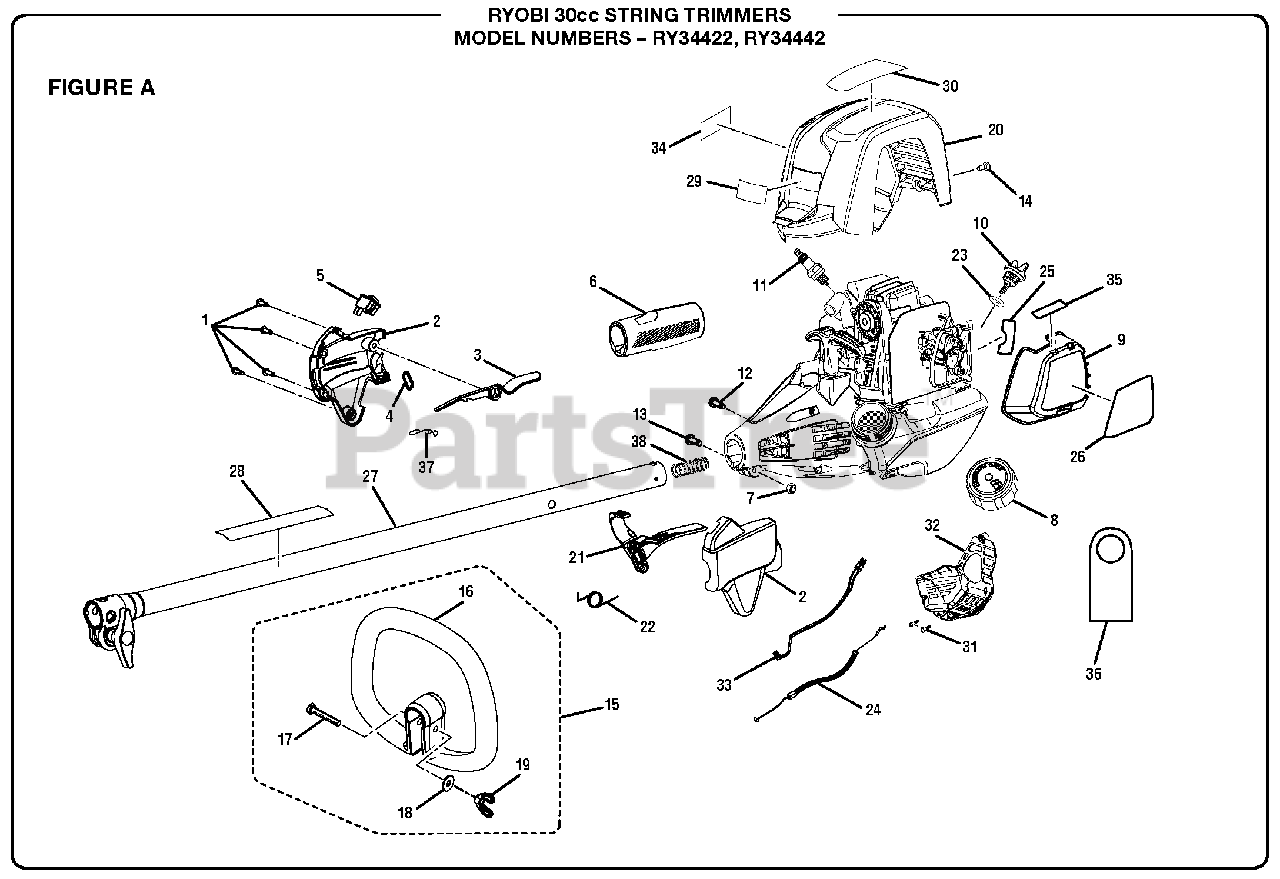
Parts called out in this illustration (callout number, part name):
1	Screw (M4 x 20 mm)
2	Control Handle Assembly
3	Trigger Lock
4	Strap Hanger
5	Switch (Momentary Contact)
6	Rear Handle
7	Hex Nut (M6.3 x 1)
8	Fuel Cap Assembly
9	Air Box Cover
10	Oil Cap/Dipstick
11	Spark Plug (Champion RY4C)
12	Screw (#8-16 x 5/16 in.)
13	Bolt (M6 x 1 x 20 mm)
14	Screw (M5 x 11 mm)
15	Front Handle Assembly
16	Front Handle
17	Bolt (1/4-20 x 40 mm)
18	Washer (1/4 in.)
19	Wing Nut (1/4-20)
20	Top Cover Assembly
21	Throttle Trigger
22	Throttle Trigger Spring
24	Throttle Cable
25	Hot Surface Label
26	Starting Label
27	Upper Boom Assembly
28	Warning Label
29	Logo Label
30	C430 Label
30	S430 Label
31	Screw (#6-19 x 1/2 in.)
32	CE Cover (Bottom Cover)
33	Lead Assembly
34	Combustion Warning Label
35	Choke Label
36	Oil Hang Tag
38	Compression Spring
